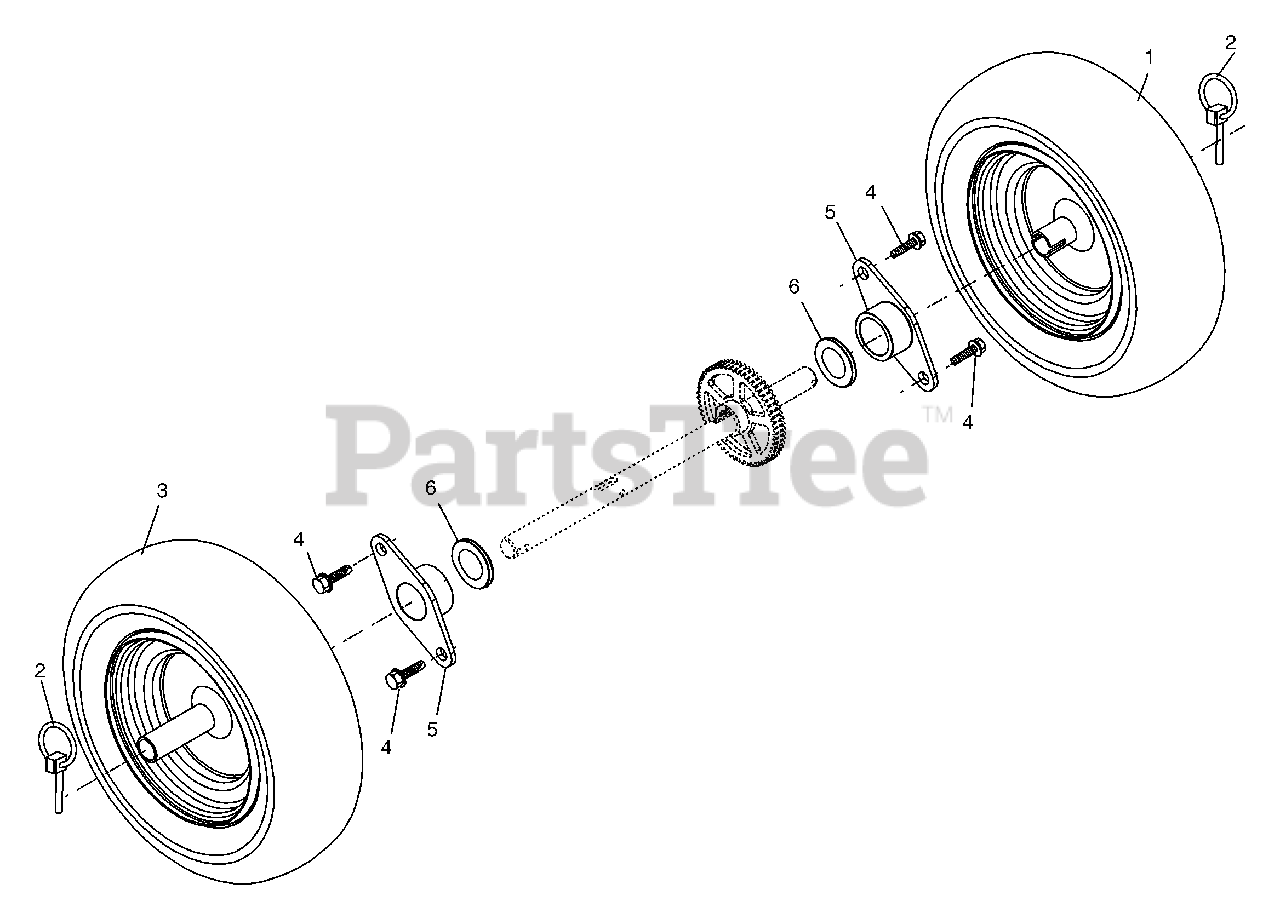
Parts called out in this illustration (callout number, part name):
1	Wheel Assembly, 16", LH
2	Pin, Klik 1/4
3	Wheel Assembly, 16", RH
4	Screw, Hex Head 5/16-18 x 5/8
5	Bearing, Axle
6	Washer, Thrust (1")
